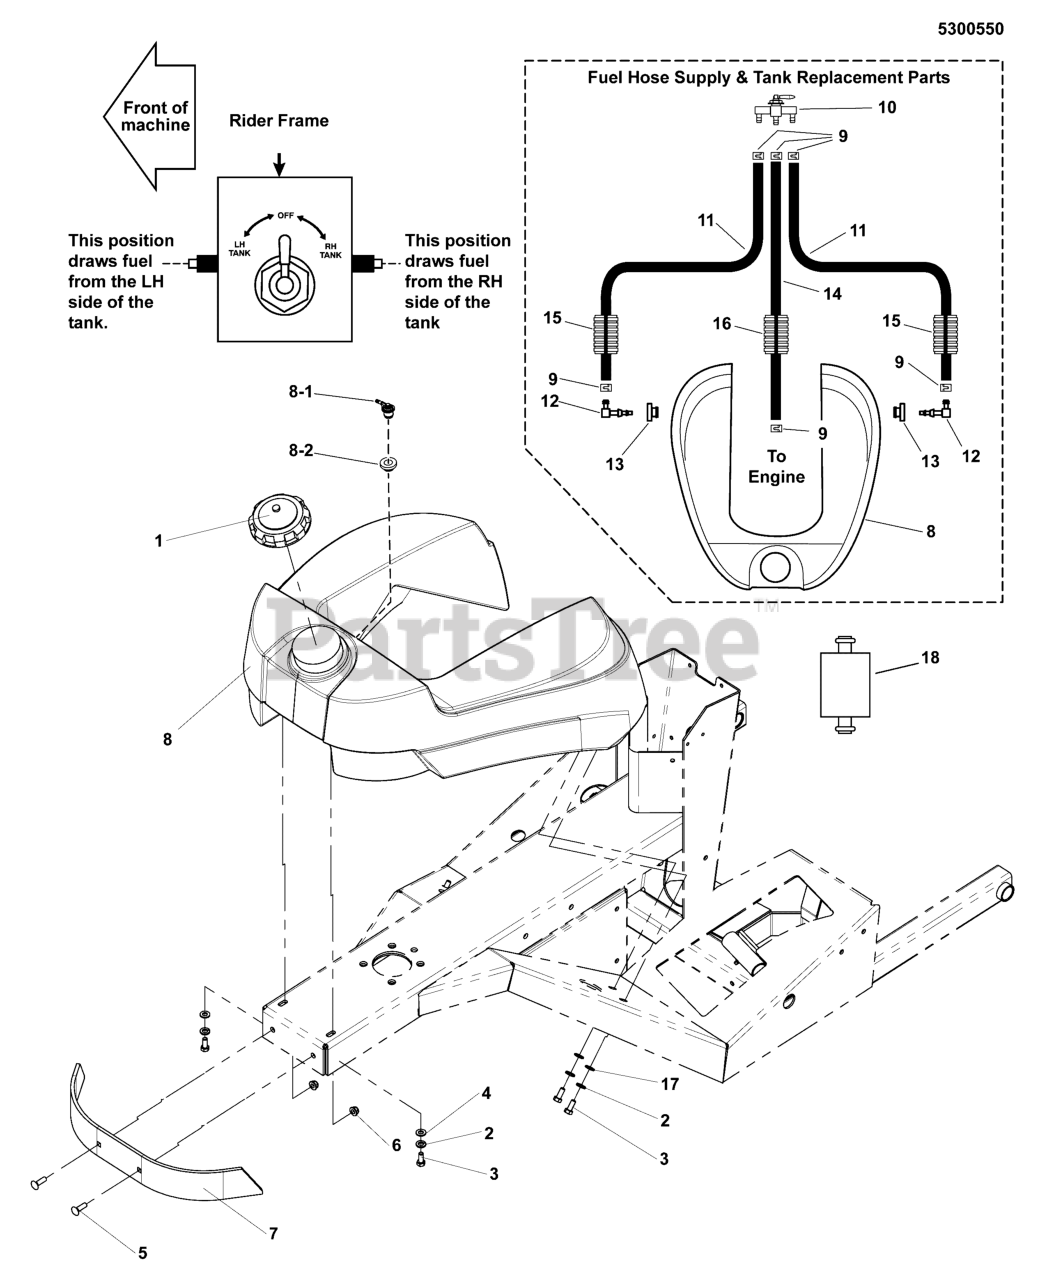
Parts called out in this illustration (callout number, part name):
1	CAP, GASOLINE, VENTED
1	CAP, FUEL TANK
2	WASHER, 5/16 LOCK CZ
3	BOLT, 5/16-18 X 3/4 GD5
4	WASHER, 5/16" SAE
5	BOLT, 5/16-18 X 1", CARRIAGE
6	NUT, 5/16-18 HEX NYLOCK FLANGE
7	BAR, BUMPER, TWR - RED
8	TANK, FUEL - TWR
8	TANK, FUEL, TWR
8-1	ASSY., REMOTE VENT - NO VALVE
8-2	GROMMET (SV)
9	CLAMP, HOSE, EXTERNAL, 1/2 - RED
10	VALVE, FUEL, STR. OUTLET
11	HOSE, FUEL, 1/4 IN, LW PRMTN X 42
12	ELBOW FITTING
13	BUSHING-FUEL TANK RED RUBBER
14	HOSE, 1/4" FUEL, 21.00"
14	HOSE, 1/4" FUEL, 28.00"
14	HOSE, 1/4" FUEL, 13.00"
15	WIRE LOOM, 1/2" ID, 39"
16	WIRE LOOM, 1/2" ID, 18"
16	WIRE LOOM, 1/2 ID, 28"
16	WIRE HOSE, 1/2" ID, 6"
17	WASHER, 5/16" USS
18	FUEL FILTER (SV)
